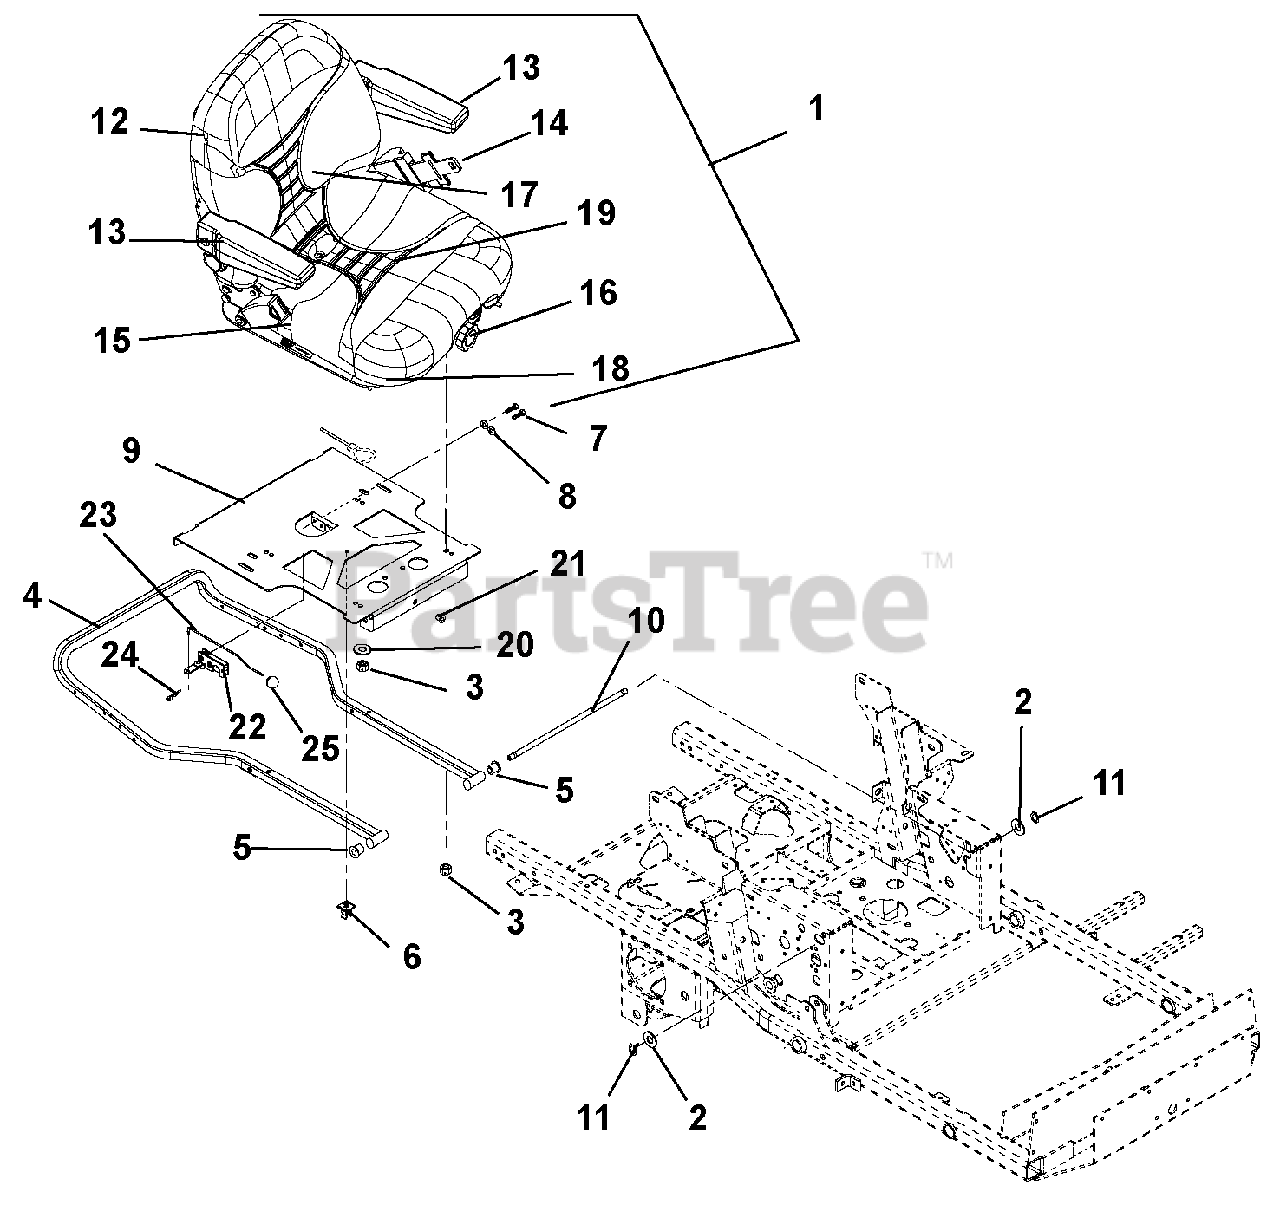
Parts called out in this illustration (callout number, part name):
1	Seat, with Seat Belt, Gray
2	Washer, Flat Steel .531 x 1.06 x .095
3	Nut, Locking Top Flange .31-18
4	Weldment, Hood Frame
5	Bushing, Flange .515 x .750 x .745 x 1.00
6	Clip, Routing
7	Bolt, Hex .25-20 x 1.00 Grade 5
8	Washer, Locking .25 x .062 Regular
9	Plate, Seat 200 XDZ with Latch
10	Rod, Seat Frame Pivot
11	Ring, Retaining External .500 x .050
12	Kit, Back Cushion, Gray
13	Kit, Armrest, Plush 5300 Pair
14	Kit, Retractable Safety Belt
15	Kit, Seat Cushion, Light Gray
16	Kit, Seat Knobs
17	Kit, Seat Back
18	Kit, Seat Slides
19	Kit, Seat, Spring and Saddle
20	Washer, Flat Steel .344 x 1.25 x .135
21	Bushing, POLYLINER-.38 SNAPIN
22	Latch, Rotary-Push To Close – 5.570
23	Rod, Seat Latch Release
24	Pin, Hair Internal .06 x .25 x 1.12
